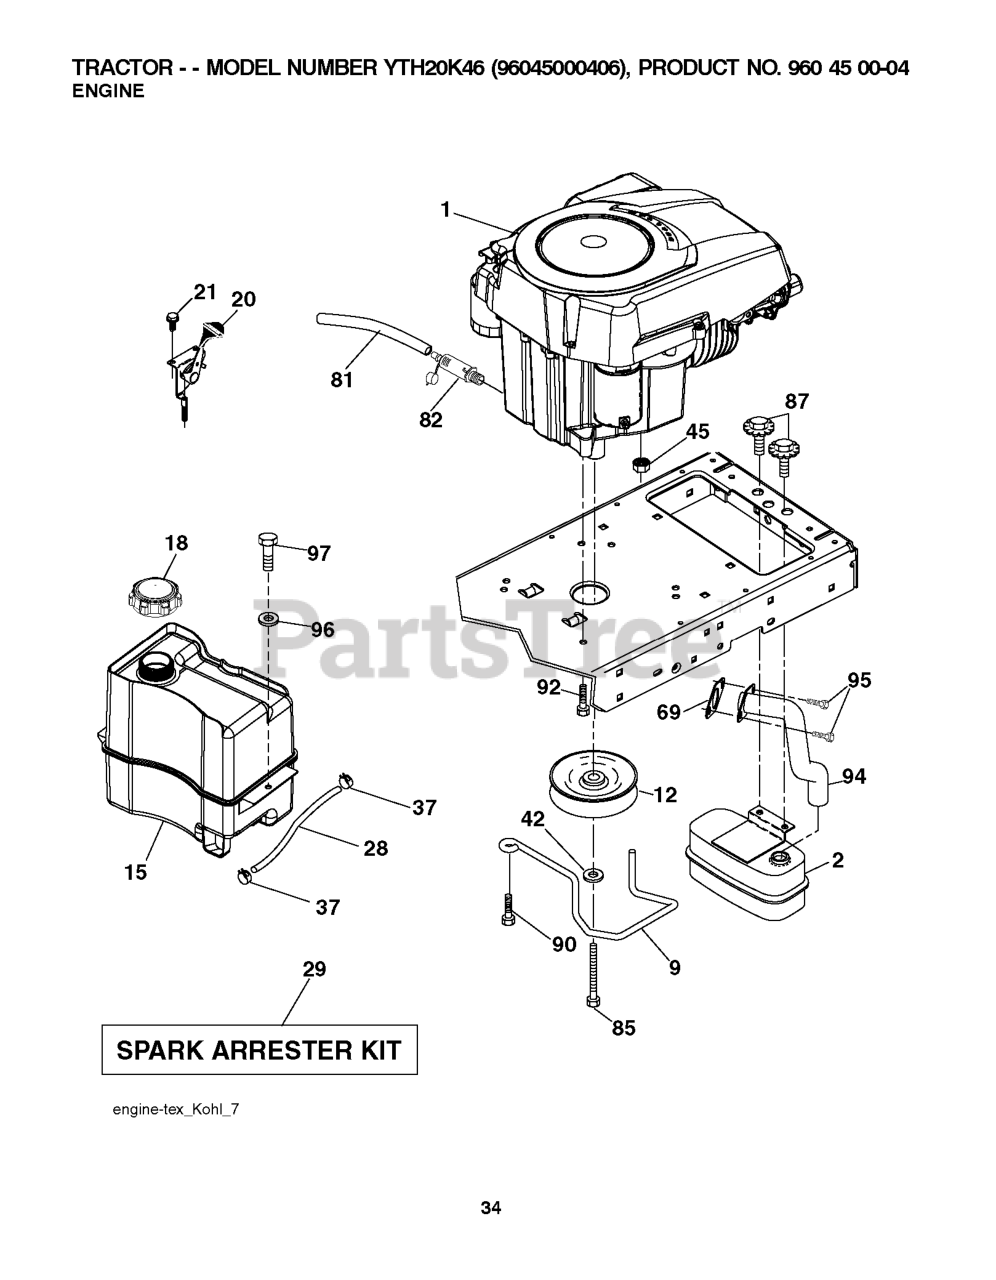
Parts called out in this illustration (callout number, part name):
2	MUFFLER.SINGLE.CYL.KOHL/B&S
9	KEEPER.BELT.ENGINE.3.25 (3 2)
12	PULLEY.ENGINE.5.0.PD
15	TANK.ASM.FUEL.FR.2.5GA.
18	FUEL CAP
20	CONTROL.TH/CK.COBRA.KO
21	SCREW.#10 X 0.750.BOS
28	LINE.FUEL.20"FRONT.EMI
29	KIT.SPARK ARRESTOR 794945 B&S
37	HOSE CLAMP
42	LOCKWASHER
45	NUT
69	GASKET.EXHAUST.KOHLER
81	TUBE, DRAIN OIL ASM.
82	PLUG DRAIN OIL EASY
85	BOLT HEX 7/16-20X4-1/4"
87	BOLT 5/1618UNC X 3/4 W/ SEMS
90	SCREW 3/8-16X1
92	SCREW 3/8-16X1
94	RP.TUBE.EXHAUST.KOHL.COURAGE
95	SCREW.SOCKET HD.5/16-1
97	SCREW HEXWSHR 1/4-20X3/4
